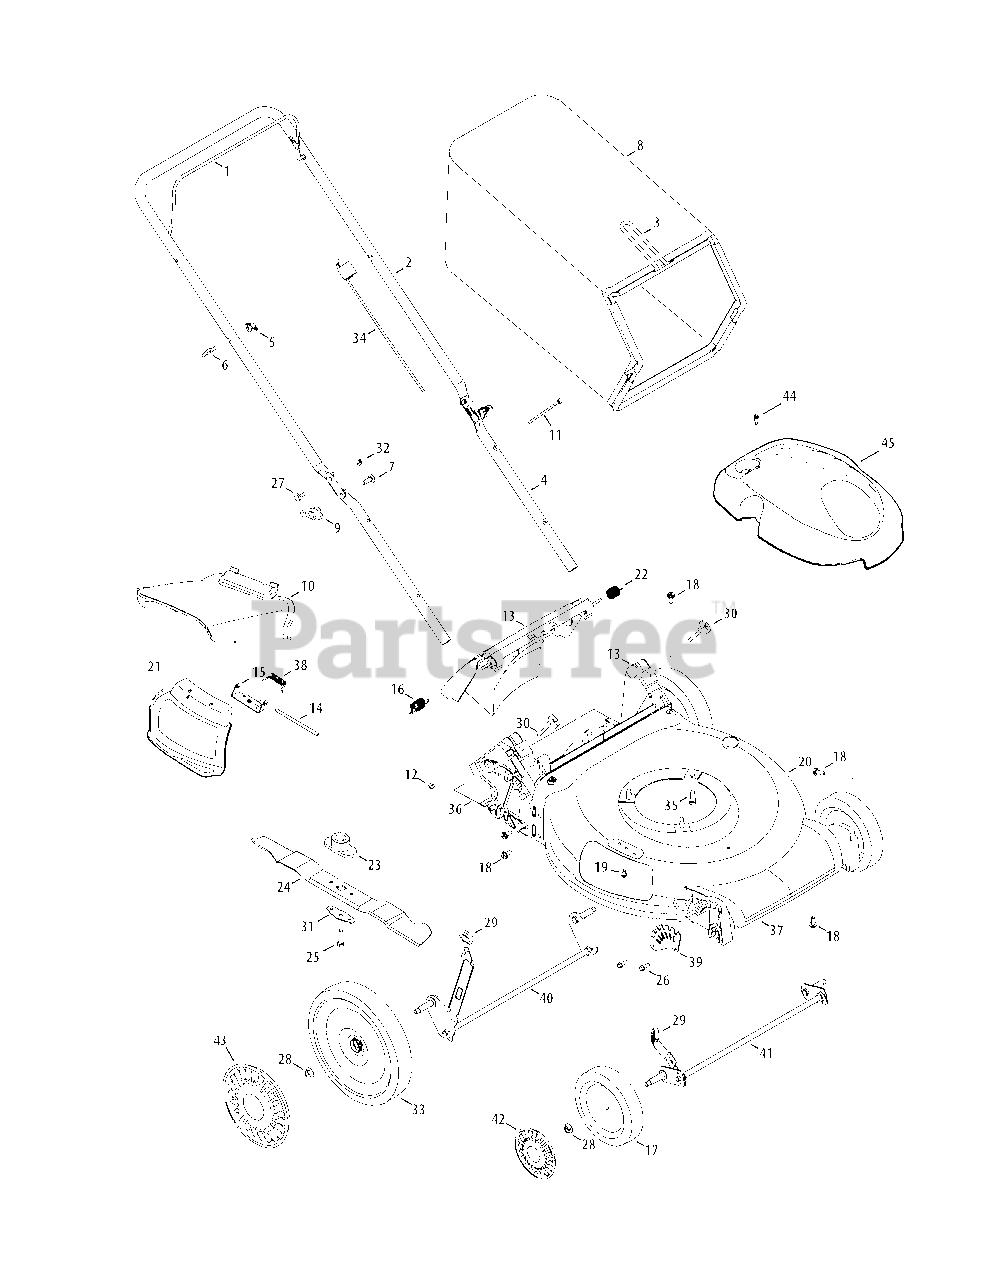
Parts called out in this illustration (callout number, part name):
1	Blade Control, Standard
1	Blade Control, Ergo
2	Upper Handle, Adjustable
2	Upper Handle, Non-Adjustable
2	Upper Handle, Ergo
3	Grass Catcher Frame
4	Lower Handle
5	Wing Nut
6	Rope Guide
7	Carriage Screw ,5/16-18
8	Grass Bag, Black
8	Grass Bag, Yardman logo
9	Wing Knob, Red
9	Wing Knob, Black
10	Side Chute
11	Cable Tie
12	Nut, Sq., 1/4-20
13	Rear Discharge Door Assembly
14	Hinge Pin
15	Chute Deflector Bracket
16	Torsion Spring - RH
17	Front Wheel Black
17	Font Wheel Gray
18	Screw, 5/16-14 x .750
19	Screw, 1/4-20 x .500
20	Deck , 21" - Red
20	Deck , 21" - Green
20	Deck , 21" - Black
21	Hinged Mulch Plug Assembly
22	Torsion Spring - LH
23	Blade Adapter, 25mm x 1.19 (Honda)
23	Blade Adapter, #6 x 1.19 w/ Star
24	Mulching Blade
25	Screw , 3/8-24 x 1.50
26	Screw, 1/4-15 x .750
27	Sldr. Screw, .375 x .126 x 1/4-20
28	Flange Lock Nut, 3/8-16
29	Adjustment Lever Knob
30	Wing Nut, Red
30	Wing Nut, Black
31	Blade Bell Support
32	Nut, Flange Lock, 1/4-20
33	Rear Wheel Black
33	Rear Wheel Gray
34	Control Cable, 36.65", Honda
34	Control Cable, 48"
34	Control Cable, 37.25"
34	Control Cable, 40"
35	TT Sems Screw, 3/8-16 x 1.0
36	Trail shield
37	Front Cover
38	Torsion Spring
39	Front Height Adjuster Plate
40	Rear Axle Assembly
41	Front Axle Assembly
42	Hubcap, 7" w/ snaps, Gray
42	Hubcap, 7" w/o snaps, Gray
42	Hubcap, 7" Yellow
43	Hubcap, 11" Gray
43	Hubcap, 11" Yellow
44	Screw, HL, #12-16 x 1.00
45	Engine Shroud M1.1 Black
45	Engine Shroud M2 Gray
45	Engine Shroud M5 Gray
